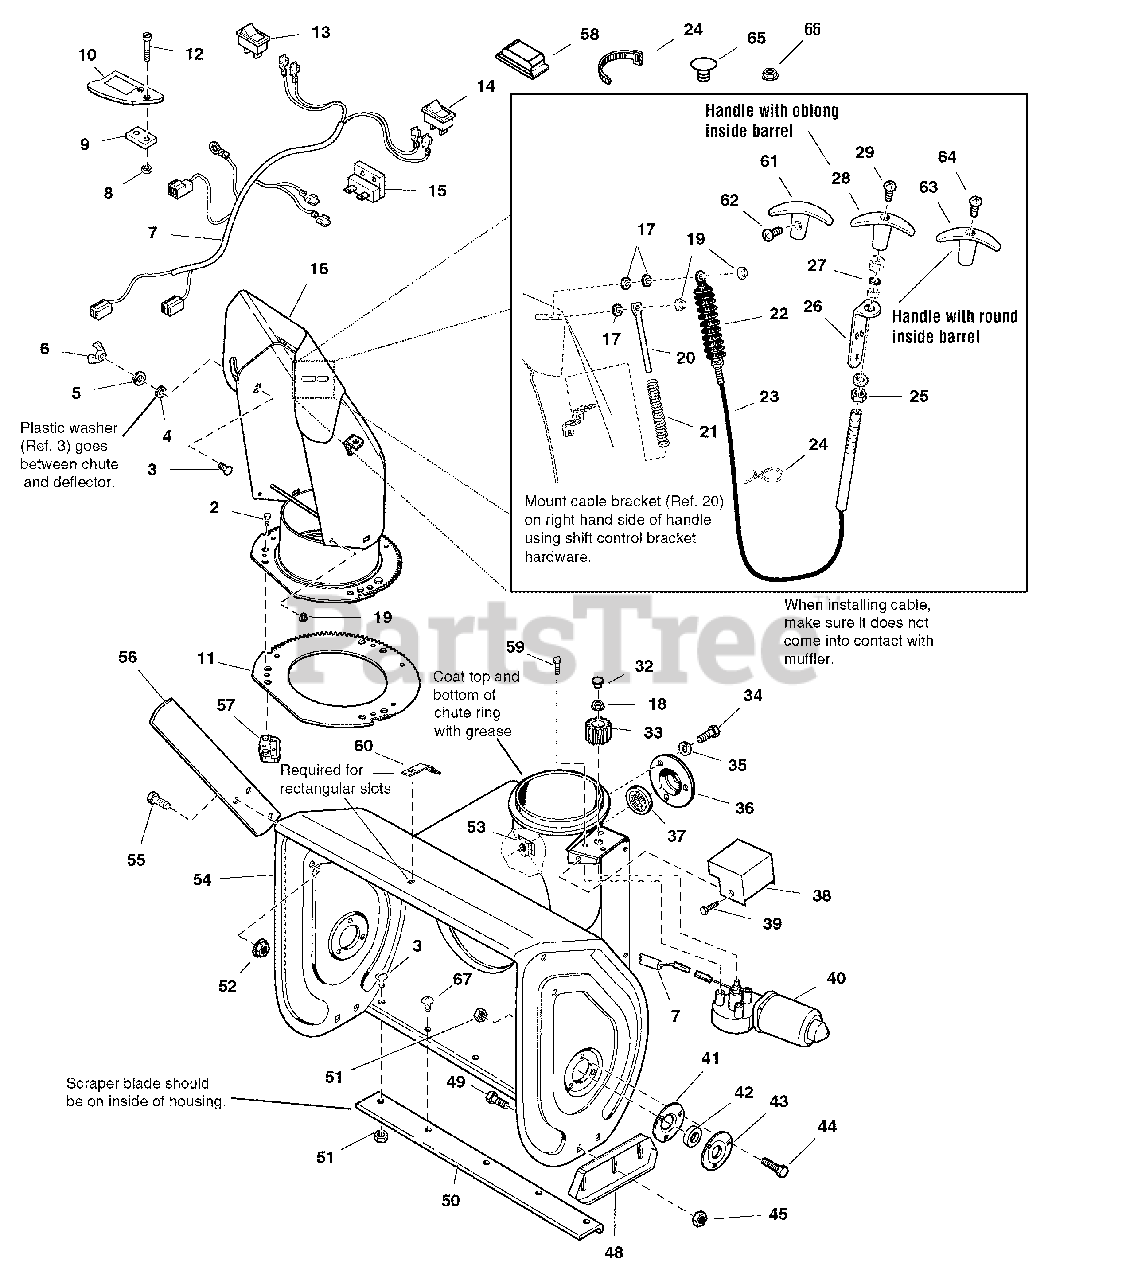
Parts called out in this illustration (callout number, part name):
2	CAPSCREW, Hex Washer Head, Plastite, #10-14 x 5/8
3	BOLT, Carriage 3/8-16 x 1
4	WASHER, Nylon
5	WASHER, 5/17, Black
6	NUT, Hex Lock ESNA, 5/16-18
7	WIRE ASSEMBLY
8	NUT, Hex Lock, 10-24, Black
9	BRACKET, Switch, Bottom
10	BRACKET, Switch, Top
11	GEAR, Chute
12	SCREW, Truss Head Phillips 10-24 x 1-5/8
13	SWITCH, Spout Rotator
14	SWITCH, Hand Warmer, Off, Warm, Hot
15	RESISTOR BLOCK
16	CHUTE & DEFLECTOR ASSEMBLY
18	NUT, KEPS Conical Washer 1/4-20
19	NUT, Push, Black
21	SPRING, Compression
22	BOOT, Water
23	CABLE & KNOB ASSEMBLY
24	CABLE TIE
25	NUT, Hex, 5/16-18
26	BRACKET, "L"
27	SEAL, Rod, Chute Deflector Cable
28	HANDLE, Cable
29	SCREW, Pan Head, #8-32 x 11/16
32	CAP, Plug Black Poly
34	CAPSCREW, Hex Head, 5/16-18 x 5/8, Black
35	LOCKWASHER, 5/16, Black
36	RETAINER, Bearing
37	BEARING, Ball
38	COVER, Pinion
39	CAPSCREW, Hex Washer Head, 1/4-20 x 1/2, Black
40	MOTOR, Electric
41	FLANGE, Bearing
42	BEARING, Cartridge
43	FLANGE, Bearing
44	CAPSCREW, Hex Head, 5/16-18 x 7/8, Black
45	NUT, ESNA Hex, 3/8-16, Black
48	SKID & SUPPORTS ASSEMBLY
49	CARRIAGE BOLT, 3/8-16 x 1, Black
50	BLADE, Scraper
51	NUT, Hex Flange Lock, 5/16, Black
52	NUT, KEPS Hex, 5/16-18, Black
53	NUT, Retainer Speed, 5/16-18
54	HOUSING & IMPELLER ASSEMBLY, 38"
55	CAPSCREW, Hex Head, 5/16-18 x 3/4, Black
56	CUTTER, Drift
57	CHUTE RETAINERS
58	BOOT, Rocker Switch
59	SCREW, SEMS Conical Washer, 1/4-20 x 7/8 DG Point, Black
60	PLATE, Reinforcement
62	SCREW, Set, Hex #10-24 x 3/8
63	HANDLE "T"
64	SCREW, Round Head
65	CAP-Plug Black Poly
66	NUT-KEPS Conical Washer 1/4-20
67	CARRIAGE BOLT, 5/16-18 x 3/4
